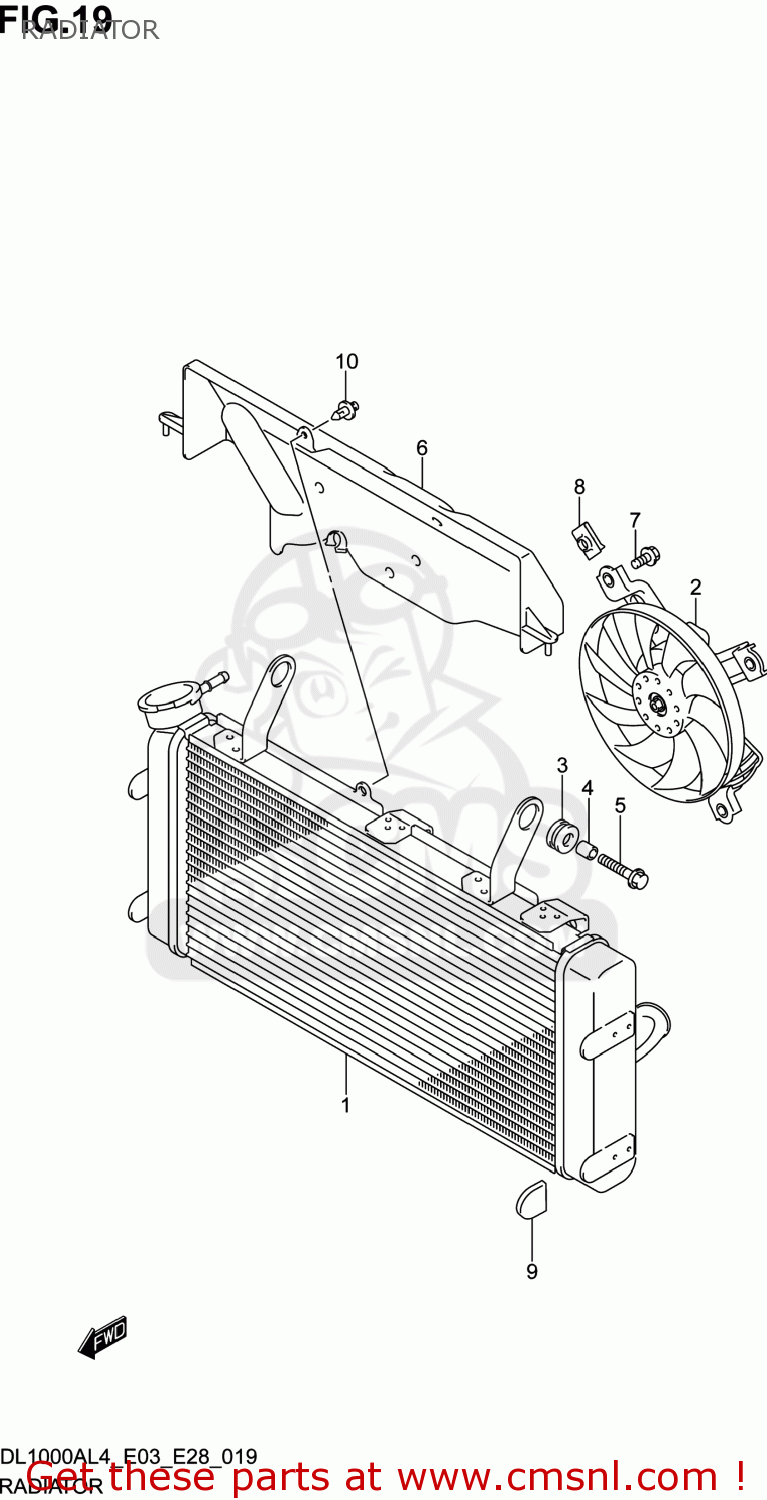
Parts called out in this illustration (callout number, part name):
1	RADIATOR ASSY,WATER
2	FAN ASSY,RADIATOR
3	CUSHION
4	SPACER(6.5X10X12)
5	BOLT(6X25)
6	SHIELD,RADIATOR HEAT
7	BOLT
8	NUT,RADIATOR FAN
9	CUSHION
10	CLIP(BLACK)
